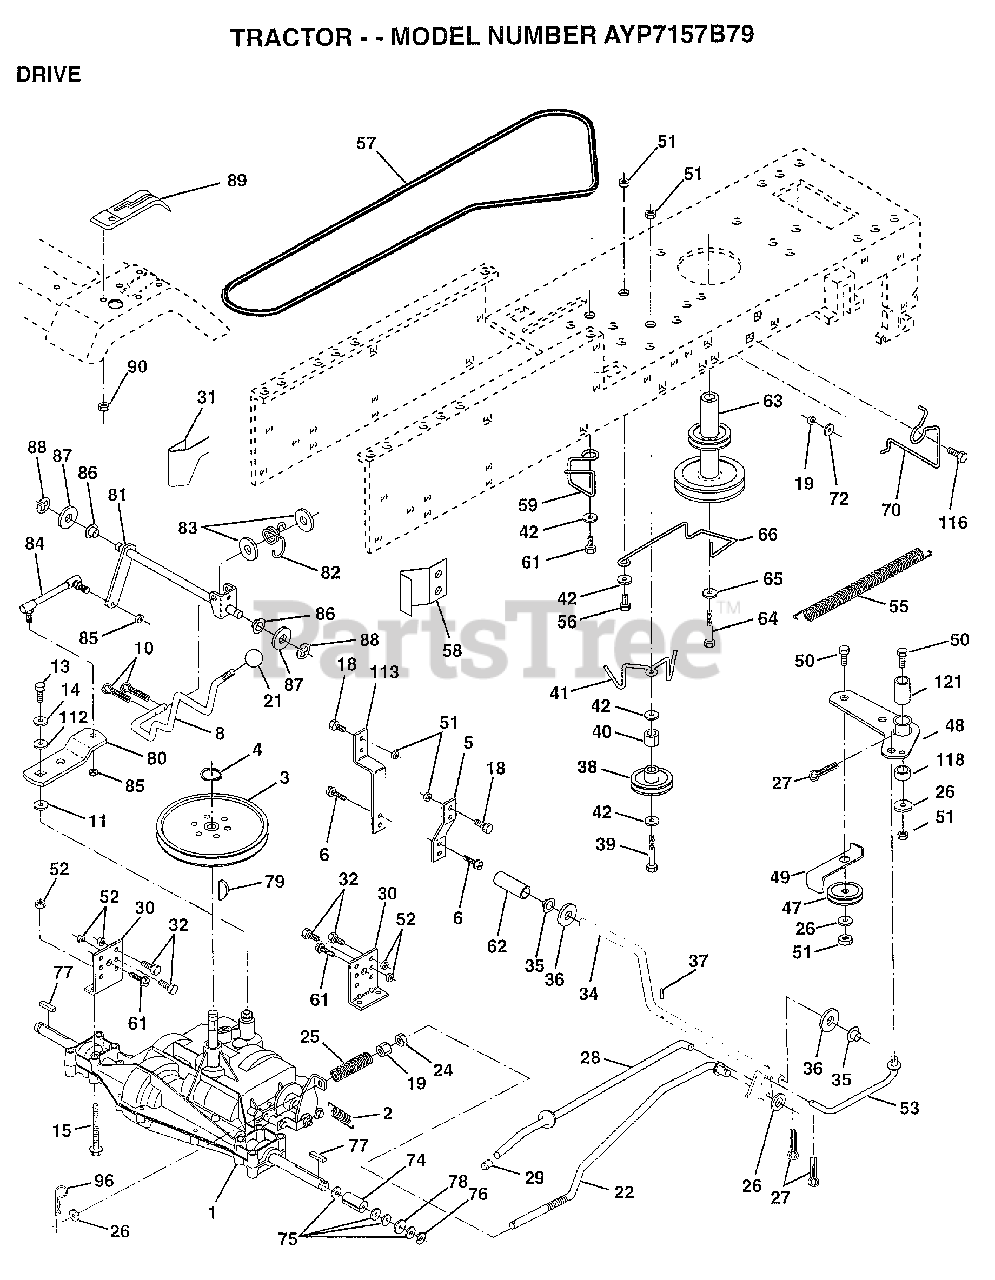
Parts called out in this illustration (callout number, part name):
2	SPRING.BRAKE.RETU
3	PULLEY TRANS
5	SPRING
6	SCREW
8	ROD SHIFT FEND LT
10	PIN COTTER 1/8
11	WASH-SHFT PLT LT
13	BOLT.1/4-28.W/PAT
14	LOCKWASHER
15	BOLT.HX.FLG.5/16
18	BOLT
19	NUT
21	KNOB T (1/2-HOLE)
22	BRAKE ROD
24	NUT
25	SPRING ROD LT
26	WASHER
27	COTTER PIN
28	ROD.BRAKE.PARK.LT
30	TRANSAXLE MTG BKT
31	"KEEPER,BELT LH T"
32	BOLT
34	SHAFT ASM-PEDAL F
35	NYLON BEARING
36	WASHER LT
38	PULLEY.IDLER.FLAT
39	BOLT
40	SPACER T
42	WASHER
48	BELLCRANK ASM
49	RETAIN BELT
52	NUT
53	"LINK, CLUTCH T"
55	"SPRING, RETURN LT"
58	"KEEPER,BELT RH T"
59	KEEPER BELT CNTSP
61	SCREW
62	PEDAL COVER T
63	PULLEY.ENGINE
64	BOLT
65	LOCKWASHER
66	KEEPER-BELT
70	KEEPER BELT ENG
72	WASHER
74	SPACER AXLE
75	WASHER
76	E-RING LT
77	SQUARE KEY
78	WASHER
80	"ARM.SHIFT.20""TIRE"
81	SHAFT.CROS.P930.
82	"SPRING,TORSION"
83	WASHER
84	"ROD.TIE.20""P930LT"
85	NUT.CNT.LOCK.1/4
86	BUSHING
87	WASHER D
88	KLIP RING
90	NUT
96	RETAINER M
112	WASHER LT
113	"STRAP,TORQUE"
116	BOLT RDHD 3/8-16
118	SPACER-BELLCRANK
121	NYLINER-CLUTCHING
